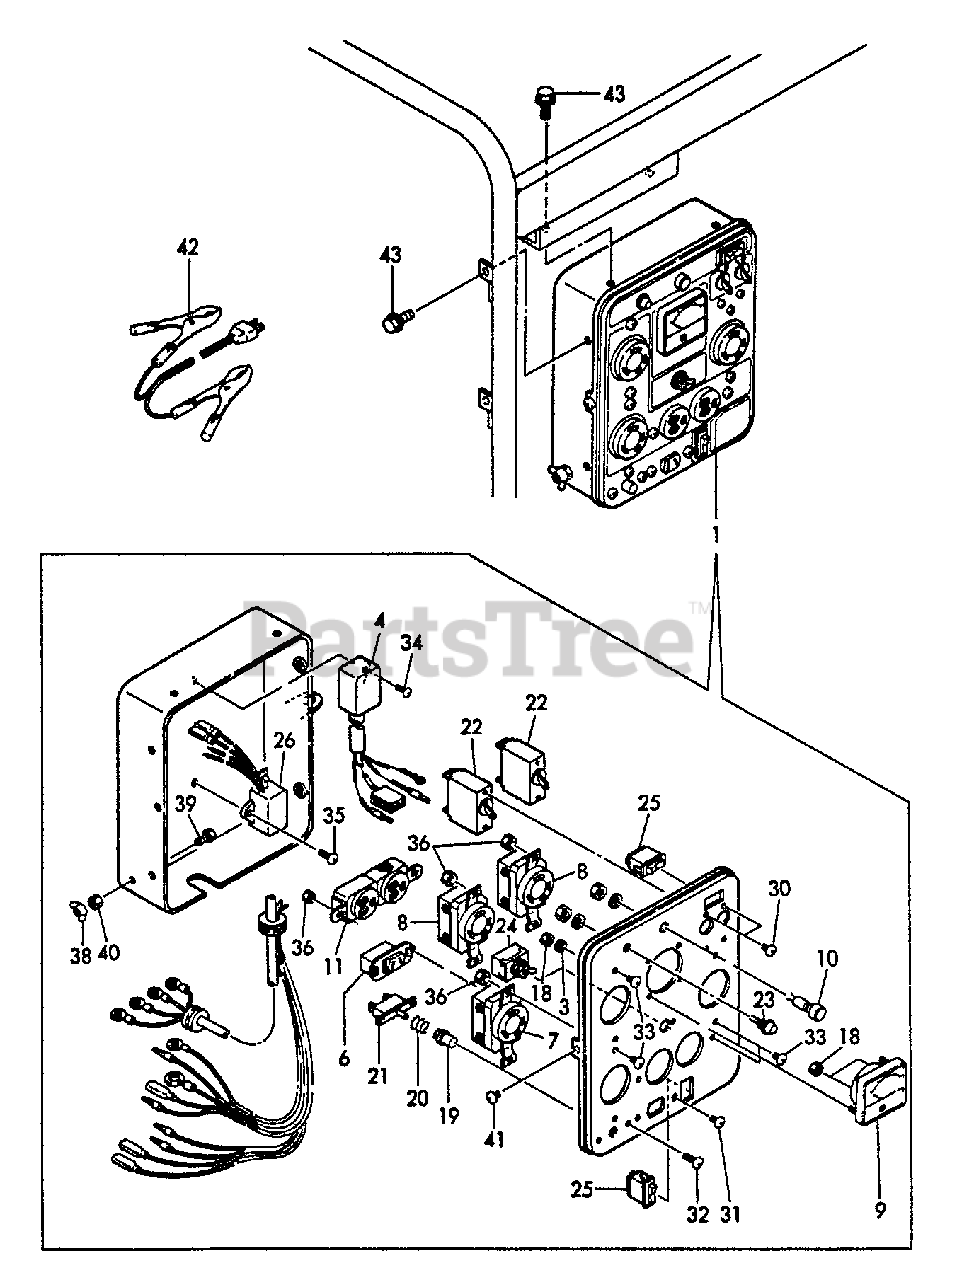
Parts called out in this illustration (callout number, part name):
1	PANEL BOX ASSY
3	LOCKWASHER
4	SENSOR, OIL
6	DC CONNECT
7	CONNECTOR
8	CONNECTOR
9	METER, VOLTAGE - 300V
10	LAMP, PILOT
11	AC CONNECT
18	NUT - 3
19	CAP, BREAKER
20	SPRING, BREAKER
21	BREAKER
22	AC BREAKER
23	LAMP, OIL ALERT
24	SWITCH
25	SWITCH
26	UNIT, SLOW-DOWN
30	SCREW - 3X6
31	SCREW - 3X6
32	SCREW - 3X14
33	SCREW - 4X6
34	SCREW - 5X10
35	SCREW - 5X10
36	NUT - 4
38	WINGNUT - 6
39	BOLT - 6X16 -- PLATED
40	LOCKNUT - 6 -- PLATED
41	SCREW - 4X6
43	BOLT - 6X8 -- PLATED
